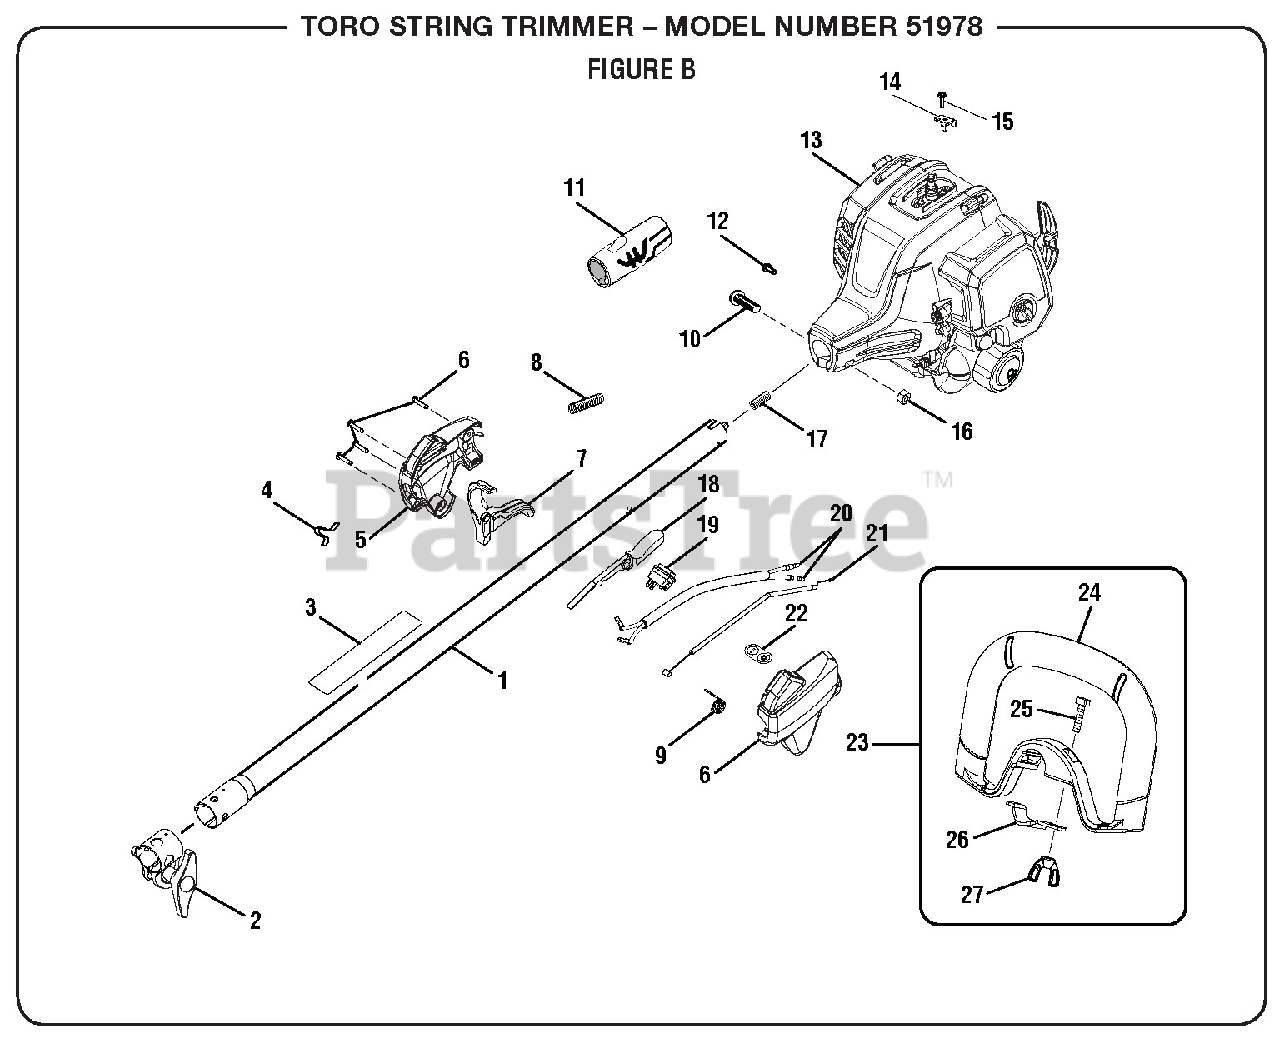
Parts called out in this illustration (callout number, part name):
1	Upper Boom Assembly
2	Boom Clamp Assembly
3	Warning Label
4	Shoulder Strap Clip
5	Control Handle Assembly
6	Screw (M4 x 20 mm, T20 Torx Hd.)
8	Corrugated Tube
9	Throttle Cable Spring
10	Screw (M6 x 30 mm)
11	Rear Handle Grip
12	Screw (M4 x 8 mm, T20 Torx Hd.)
13	Powerhead Assembly
14	Throttle Cable Clamp
15	Screw (M4 x 16 mm)
16	Hex Nut (M6.3 x 1)
17	Compression Spring
18	Trigger Lock
19	On/Stop Switch
20	Lead Assembly
21	Throttle Cable
22	On/Stop Label
23	Front Handle Assembly
24	Front Handle w/Grip
25	Screw (1/4-20 x 1 in., Sq. Hd.)
26	Front Handle Clamp
27	Wing Nut (1/4-20)
